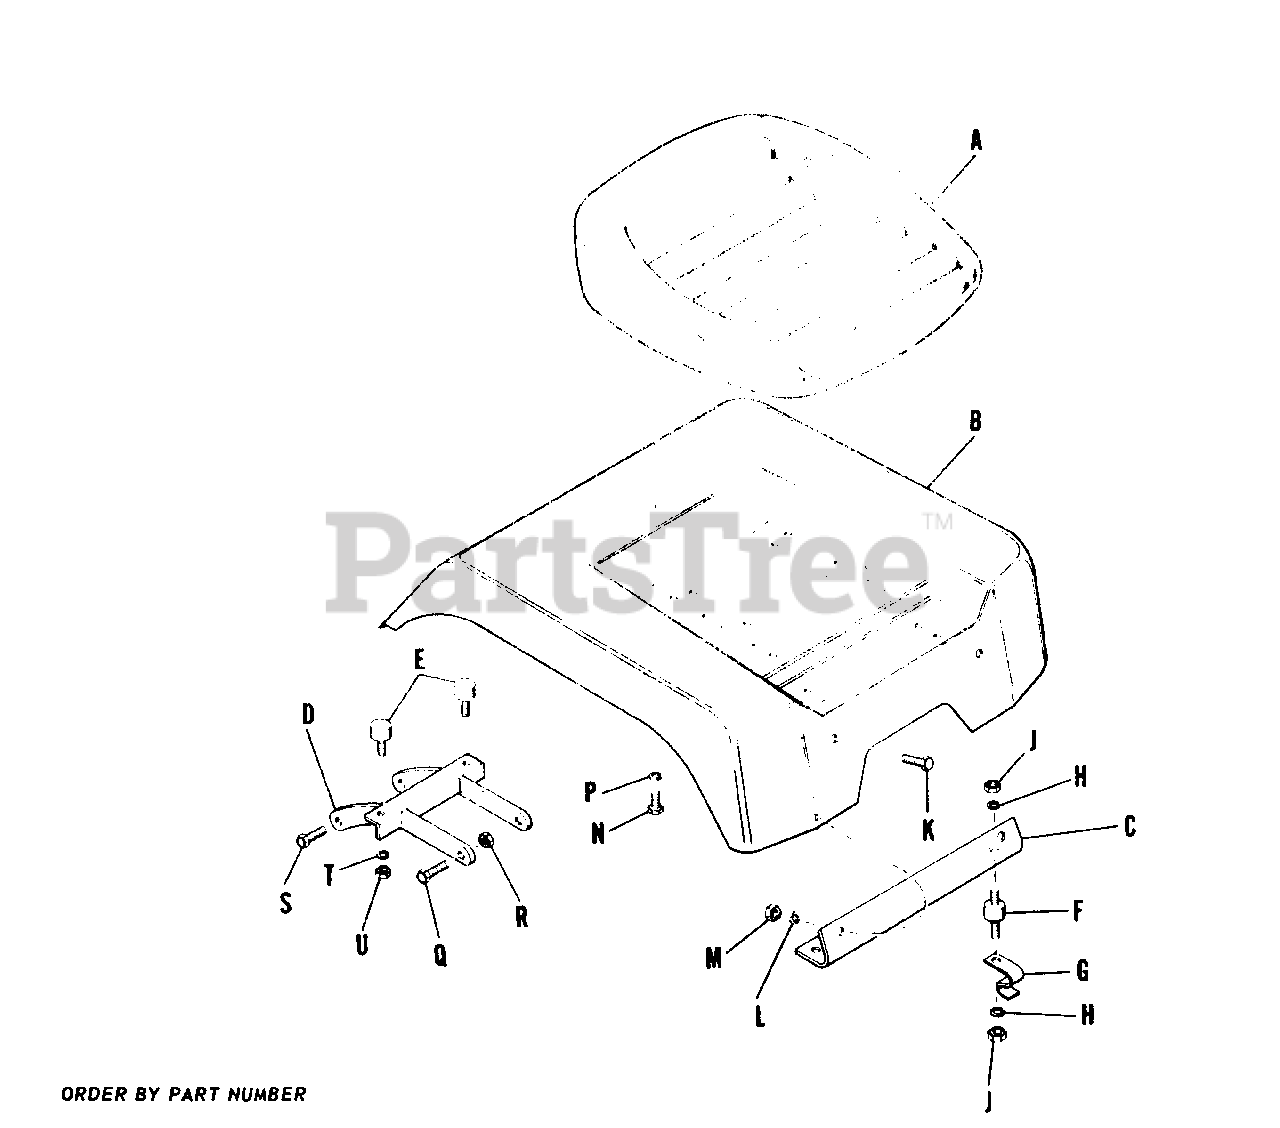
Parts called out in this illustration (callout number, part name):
A	Seat Assembly
B	Seat Deck Assemly
C	Seat Deck Bracket, Front
D	Pivot Arm Assembly
E	Sea Deck Connector, Rear
F	Cushioin Connector, Front
G	Spring Clip
H	Lock Washer, 5/16"
J	Hex Nut, Full, 5/16"-18
K	Hex. Head Capscrew, 5/16"18 x 5/8" lg.
L	Lockwasher, 5/16"
M	Hex. Nut. Full, 5/16"-18
N	Hex. Head capscrew, 5/16"18 x 5/8" lg.
P	Lockwasher, 5/16"
Q	Hex. Head Capscrew, 5/16"-18 x 5/8" lg.
R	Hex. Locknut, Full, 3/8"-16
S	Hex. Head Capscrew, 3/8"-16 x 1"
T	Lockwasher, 5/16"
U	Hex, Nut. Full, 5/16"-18
